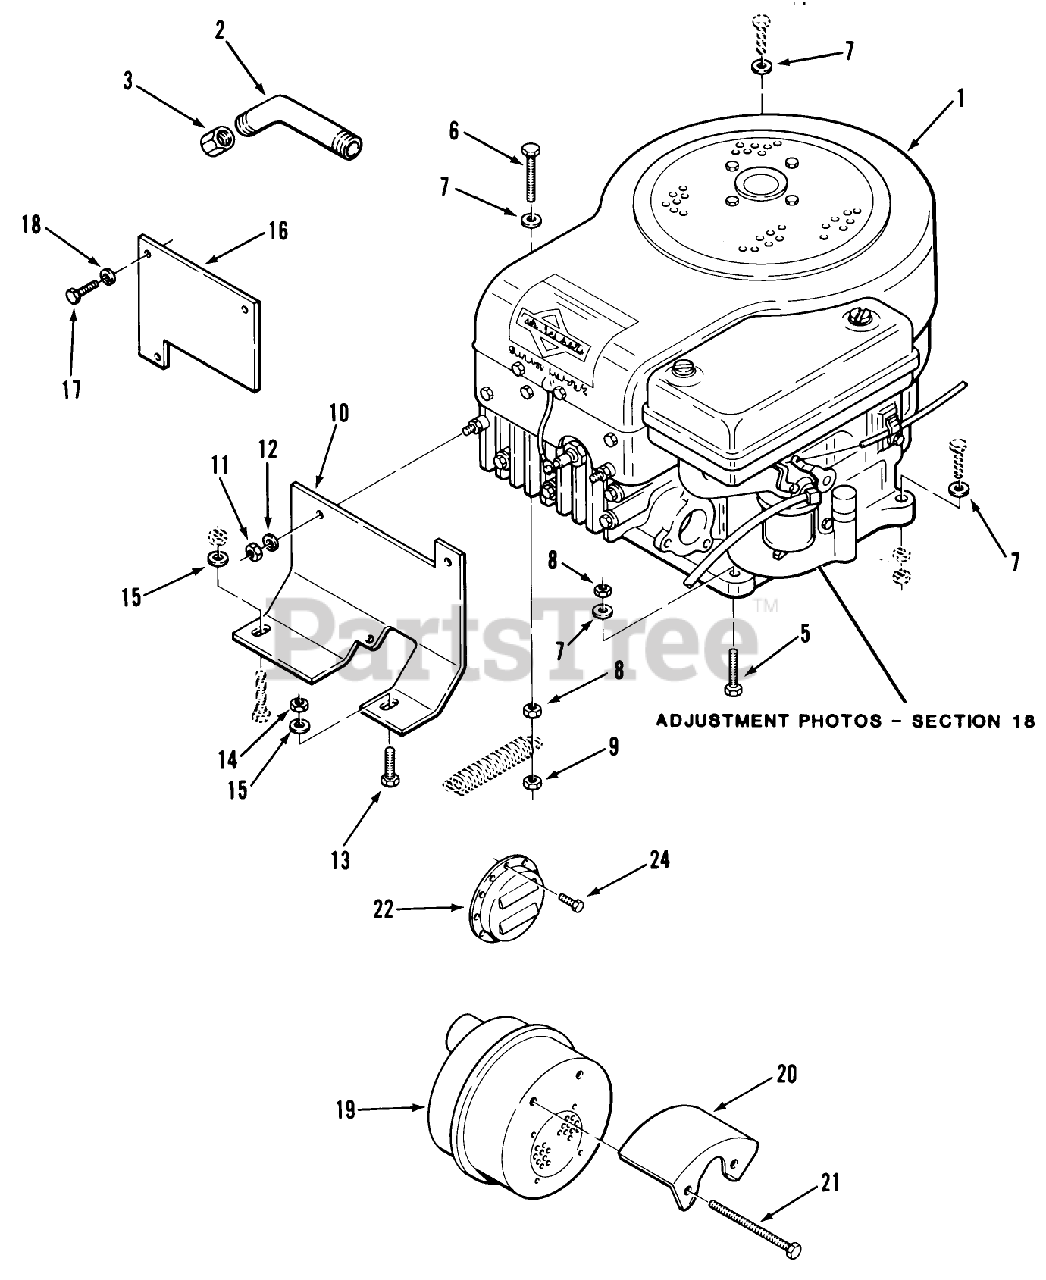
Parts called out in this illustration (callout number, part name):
1	Engine-8 HP BS Model 190702 Type 2176-01 108-R Only
7	WASHER 5/16 SAE
22	Louvered Deflector
